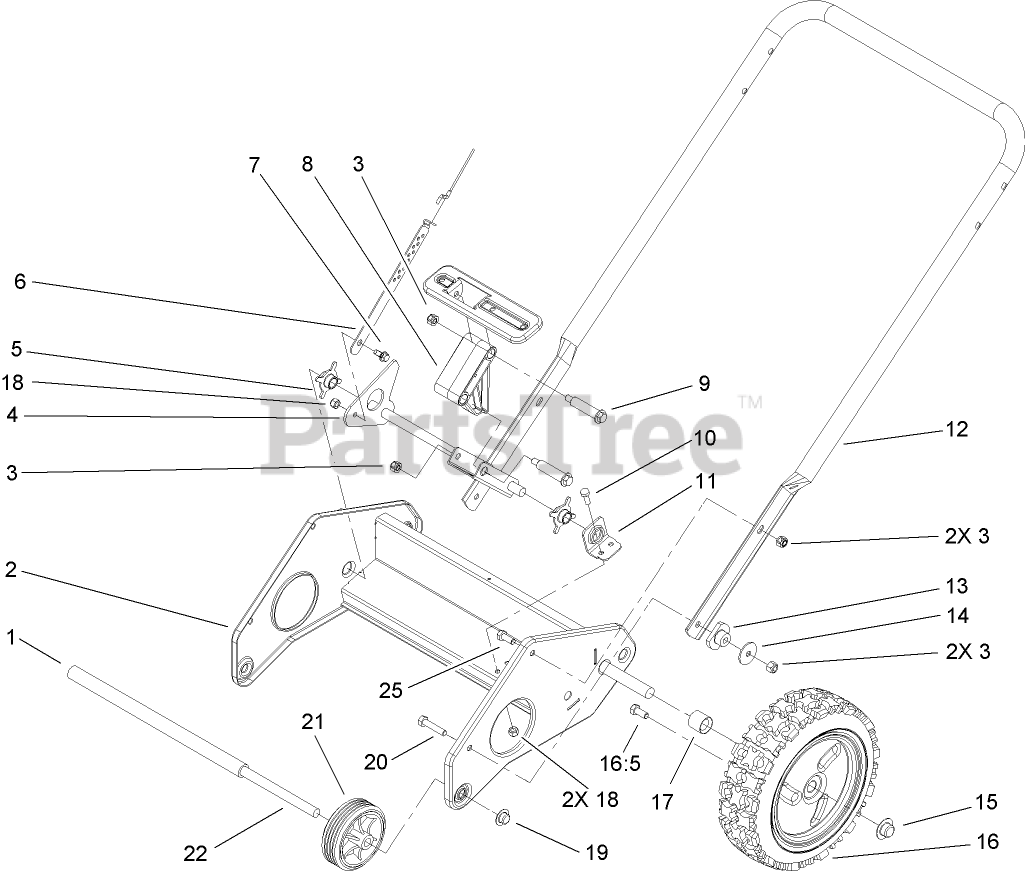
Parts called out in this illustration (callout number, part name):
1	SPACER-PLASTIC
2	WHEELFRAME ASM
3	NUT-LOCK, NI
4	PIVOT ASM
5	BUSHING-ROD, PIVOT
6	ADJUSTER-CABLE, PIVOT
7	SCREW-SHOULDER
8	BLOCK-PIVOT
9	BOLT-SHOULDER
10	SCREW-HH
11	SUPPORT-ROD, PIVOT
12	HANDLE-LOWER
13	BUSHING-PIVOT
14	WASHER-FLAT
15	NUT-PUSH
16	WHEEL ASM
16:5	SCREW-HWH
17	SPACER-AXLE, REAR
18	NUT-LOCK, NI
19	NUT-PUSH
20	SCREW-HH
21	TIRE AND WHEEL ASM
22	AXLE-FRONT
25	SCREW-HH
